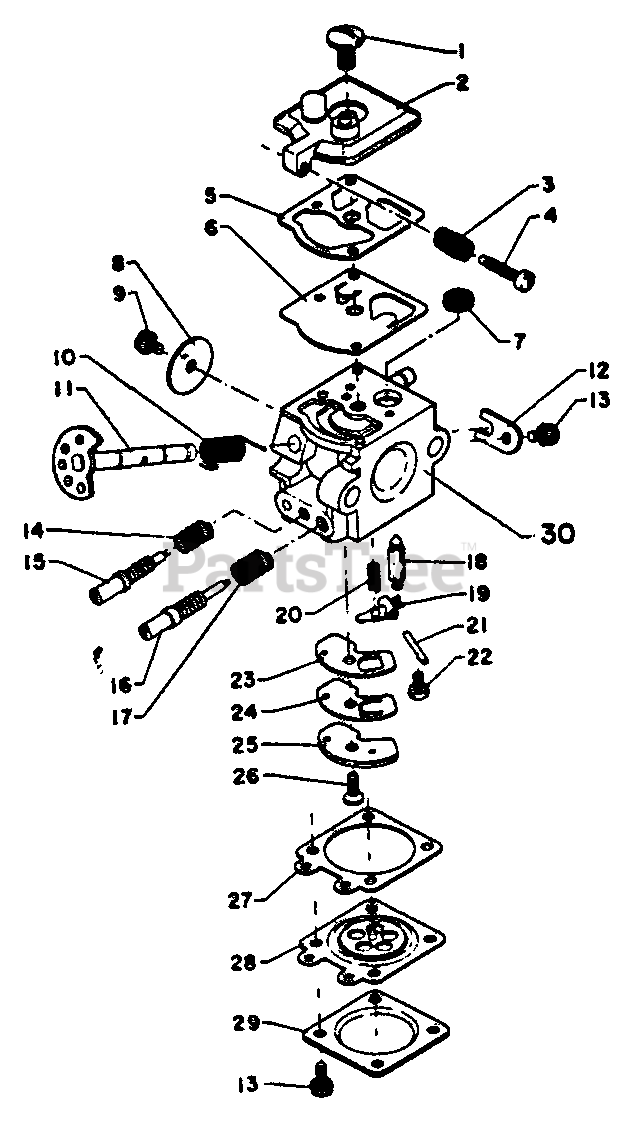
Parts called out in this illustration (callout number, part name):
1	SCREW, PUMP COVER
2	COVER, PUMP
3	SPRING, IDLE ADJUST
4	SCREW, IDLE ADJUST
5	GASKET, PUMP
6	DIAPHRAGM, PUMP
7	STRAINER
8	VALVE, THROTTLE
10	SPRING, THROTTLE RETURN
11	SHAFT, THROTTLE
12	CLIP, THROTTLE SHAFT
14	SPRING, IDLE ADJUST
15	NEEDLE - LOW SPEED
16	NEEDLE - HIGH SPEED
18	VALVE, INLET NEEDLE
19	LEVER, METERING
20	SPRING, METERING LEVER
21	PIN, METERING LEVER
22	SCREW, METERING LEVER PIN
23	GASKET, CIRCUIT PLATE
24	VALVE, CHECK
25	PLATE, CIRCUIT
26	SCREW, CIRCUIT PLATE
27	GASKET, METERING
28	DIAPHRAGM, METERING
29	COVER, METERING
30	BODY, CARBURETOR
